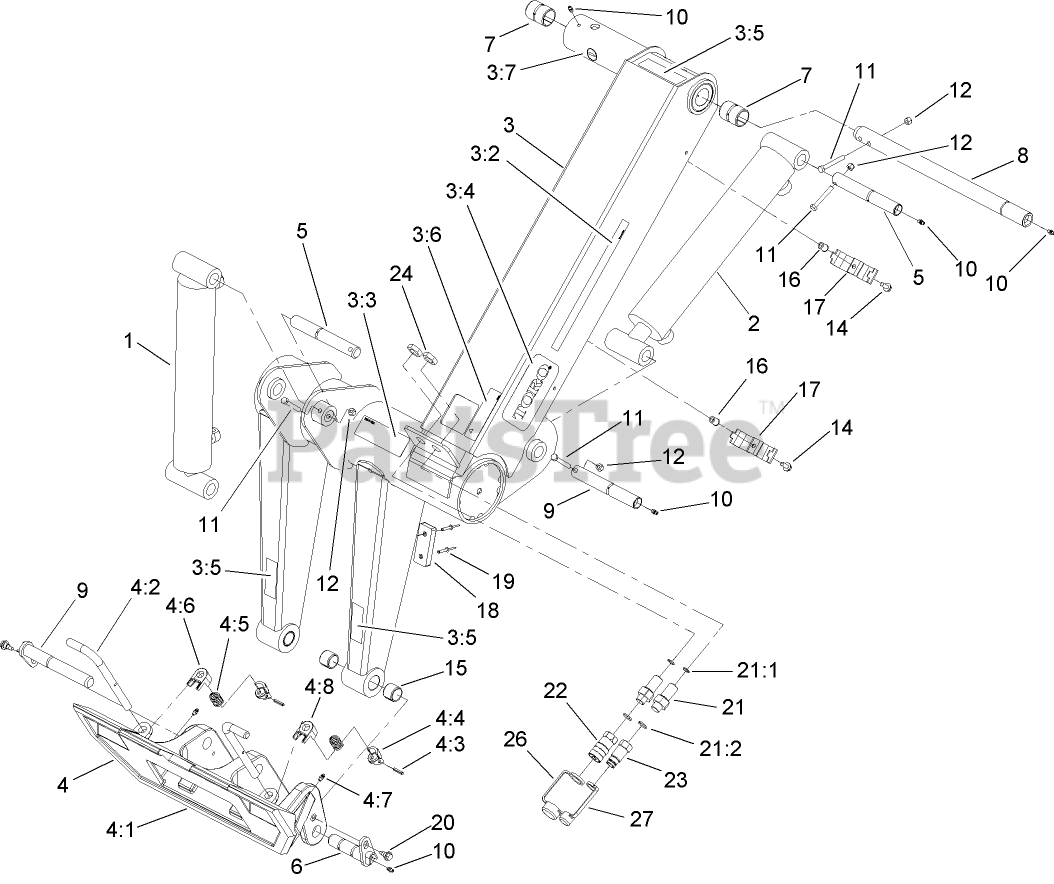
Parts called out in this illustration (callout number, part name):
1	CYLINDER-HYD
2	CYLINDER-HYD
3	LOADER ARM ASM
3:2	DECAL-MODEL
3:3	DECAL-CAUTION
3:5	DECAL-PINCH
3:6	DECAL-CAUTION
3:7	DECAL-GREASE
4	QUICK ATTACH ASM
4:1	MOUNT-QTACH
4:2	PIN-LOCKING
4:3	PIN-GROOVED
4:5	SPRING-COMPRESSION
4:6	STOP-RH
4:7	FITTING-GREASE
4:8	STOP-LH
5	PIN-PIVOT
6	PIVOT PIN ASM
7	BUSHING-TENSION, LOADER ARM
8	PIN-PIVOT, LOADER ARM
9	PIVOT PIN ASM
10	FITTING-GREASE
11	SCREW-HH
12	NUT-LOCK, NI
14	SCREW-HH
15	BUSHING-TENSION
16	NUT-INSERT
17	CLAMP-HOSE
18	BUMPER-RUBBER
19	RIVET-POP
20	BOLT-SHOULDER
21	UNION-BULKHEAD
21:1	O-RING
21:2	O-RING
22	COUPLER-FEMALE
23	NIPPLE-CONNECTOR
24	NUT-BULKHEAD
26	CAP-DUST
27	PLUG-DUST
